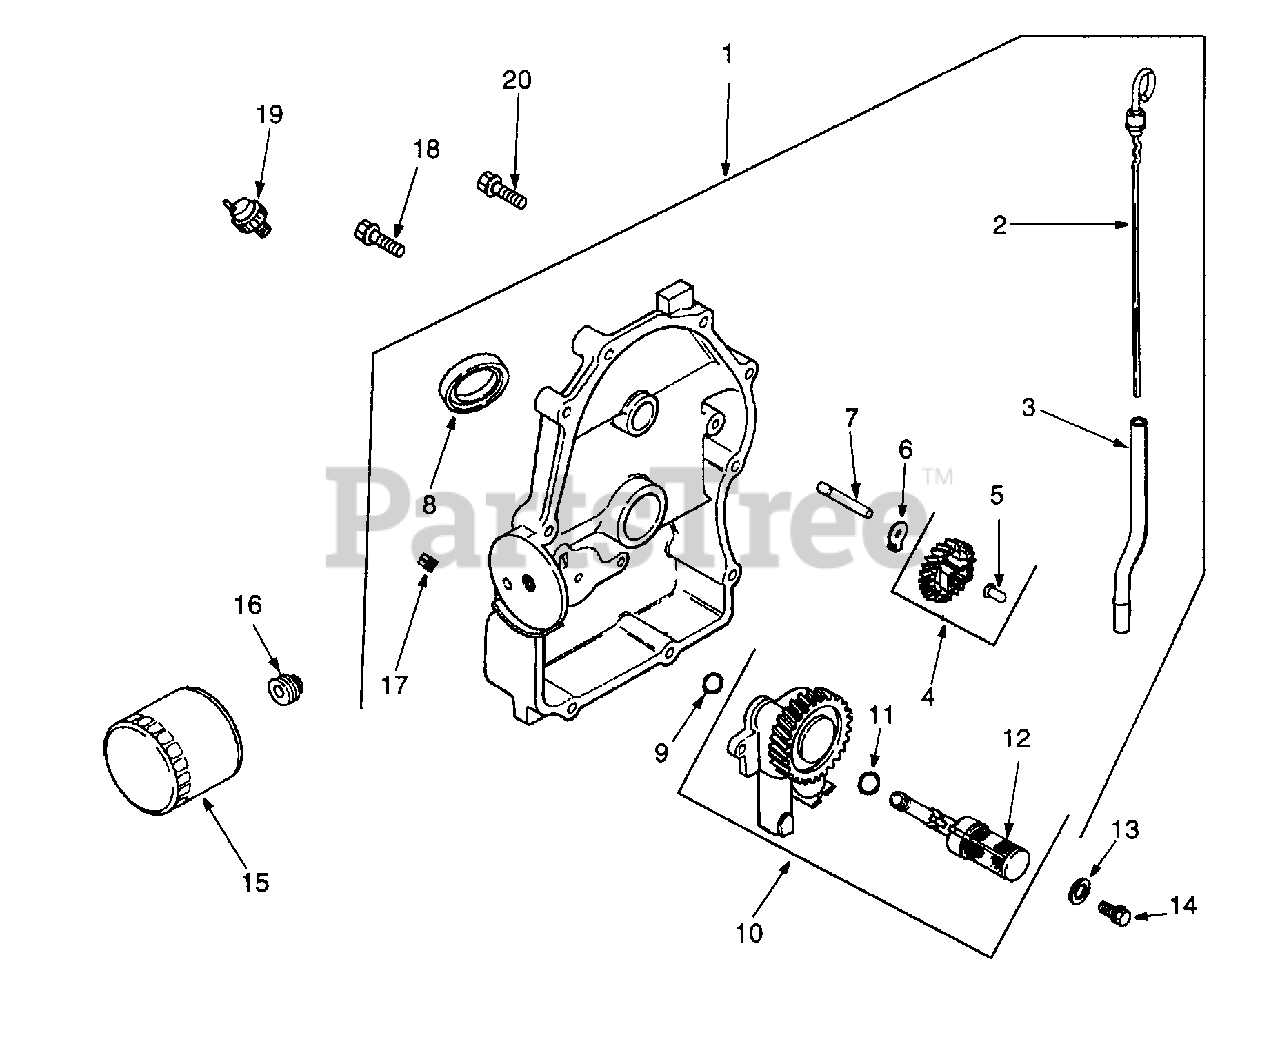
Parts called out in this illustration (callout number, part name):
1	Plate, Closure Assembly
2	Dipstick
3	Tube, Dipstick
4	Kit, Governor Gear
5	Pin, Governor Regulating
6	Tab, Locking
7	Shaft, Governor Gear
8	Seal, Oil (PTO End)
10	Oil Pump Assembly
11	O-Ring, Oil Pick-Up
12	Pick-Up, Oil
13	Washer, Plain
14	Screw, Hex Flange M6 x 1 x 25
15	Filter, Oil
16	Nipple, Oil Filter
17	Plug, Pipe 1/8"
18	Screw, Hex Flange M8 x 1.25 x 45
19	Switch, Pressure
20	Screw, Hex Flange M8 x 1.25 x 45
